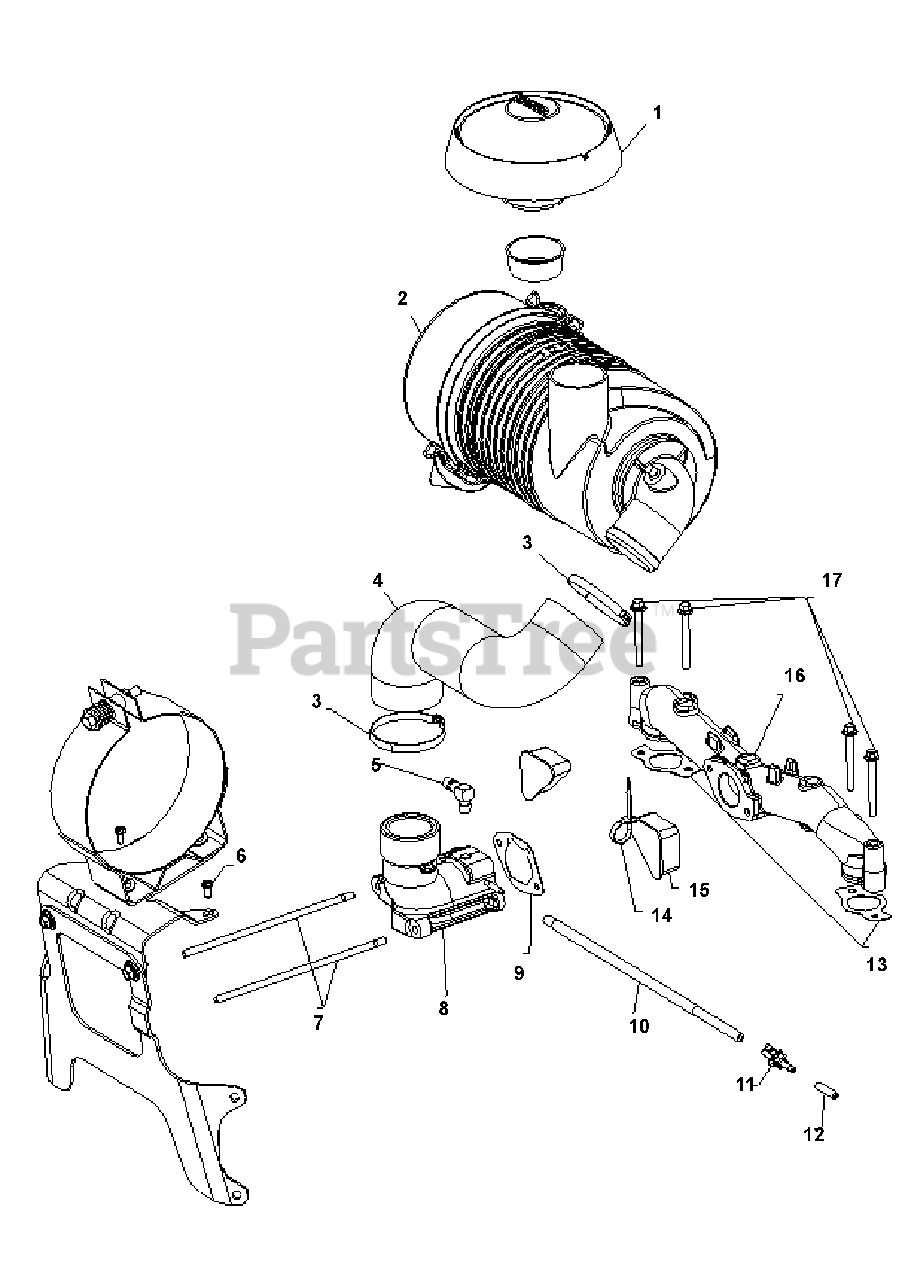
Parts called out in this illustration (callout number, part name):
4	Air Cleaner Hose
5	Hose Connector
6	Tap Screw, #8-18 x 1/2
7	Stud, M6 x 1.0 x 122
9	Air Cleaner Base Gasket
10	Evaporative Hose, 20"
11	Evaporative Connector
13	Intake Manifold Gasket
15	Blower Housing Cover
16	Intake Manifold
17	Flange Screw, M6 x 1.0 x 55
